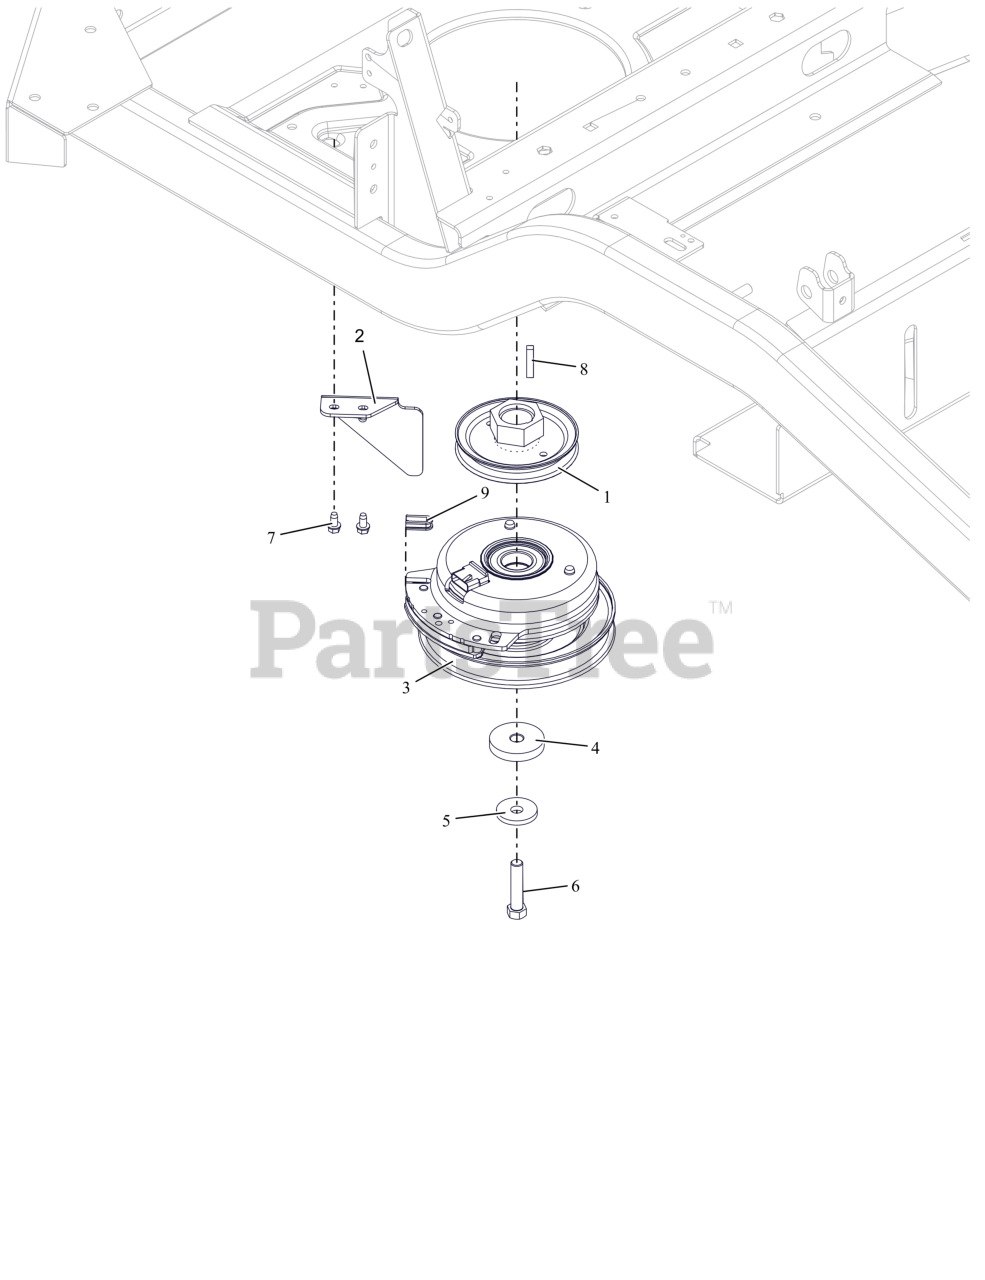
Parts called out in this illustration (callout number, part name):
1	WLDMT,PULLEY-4.50ODX1.127
2	BRKT- CLUTCH STOP
3	CLUTCH- WARNER 1.125 PT-ZX
4	SPACER, .474/.459X2.00X.350
5	WASHER, 7/16" SPRING DISK
6	BLT, HEX .44-20X2.00 G8 ZCC NT
7	SCR-TAP .25-20X.50 HWH ZCC
8	KEY-SQ .25 X 1.25 X .25 SAE
9	BSHG, CLUTCH
